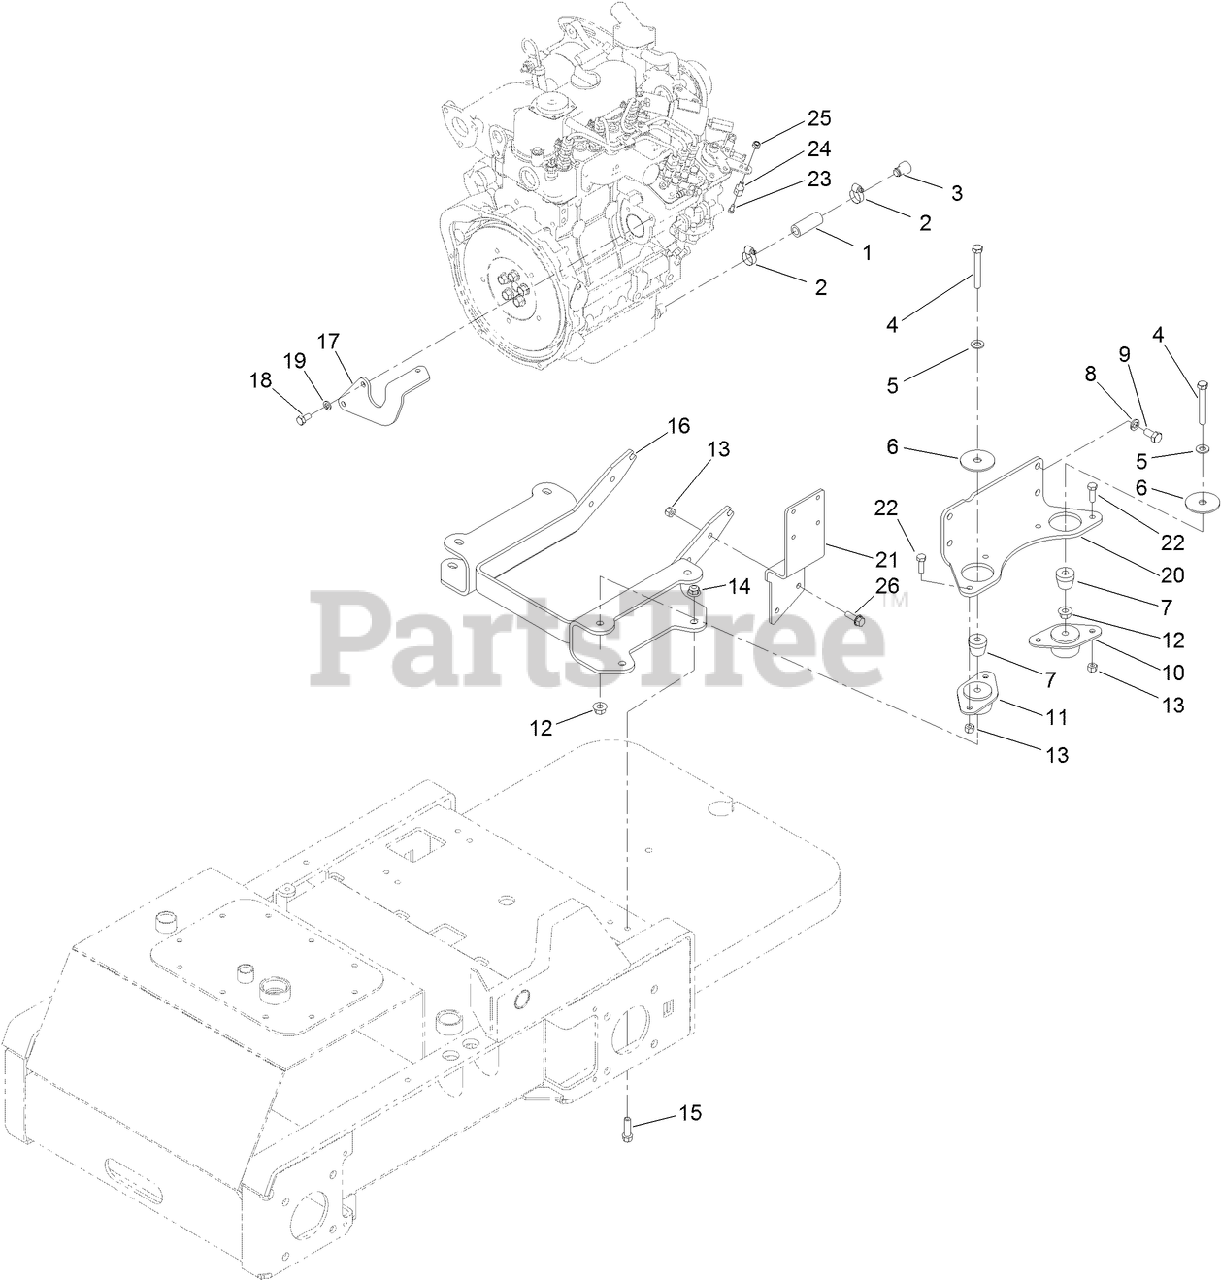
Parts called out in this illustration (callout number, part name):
1	HOSE-FUEL
2	CLAMP-HOSE
3	PLUG-OIL
4	SCREW-HH
5	WASHER-FLAT
6	WASHER-SNUBBING
7	SNUBBER-ENGINE MOUNT
8	WASHER-LOCK, SPRING
10	MOUNT-ENGINE
11	MOUNT-ENGINE
12	NUT-LOCK, FLANGE
13	NUT-LOCK, NI
14	NUT-HF, NI
15	SCREW-TAPTITE
16	MOUNT-ENGINE
17	MOUNT-SOLENOID
18	BOLT
19	WASHER-LOCK
20	PLATE-MOUNT, ENGINE
21	MOUNT-FILTER, FUEL
22	SCREW-HH
23	SCREW-HH
24	SWIVEL-CABLE, THROTTLE
25	NUT-LOCK, NI
26	SCREW-HHF
